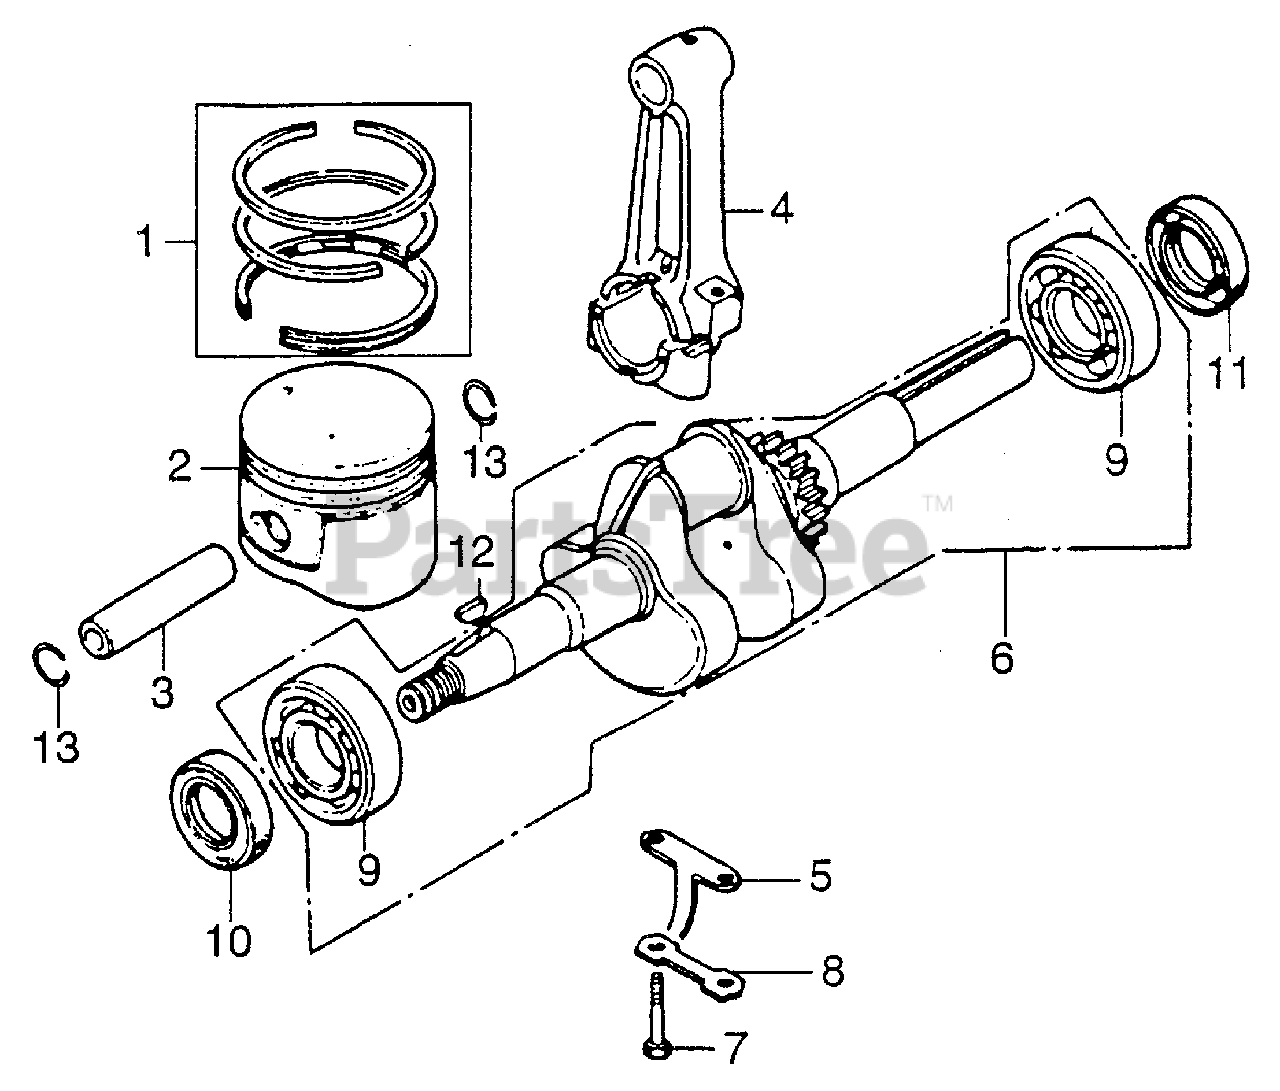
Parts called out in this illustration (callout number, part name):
1	RING SET, PISTON (STD)
1	RING SET, PISTON (OS 0.25) (OS)
1	RING SET, PISTON (OS 0.50) (OS)
1	RING SET, PISTON (0.75) (OS)
2	PISTON (STD)
2	PISTON (OS 0.25) (OS) (NOT AVAILABLE)
2	PISTON (OS 0.50) (OS)
2	PISTON (0.75) (OS)
3	PIN, PISTON
4	ROD, CONNECTING
5	DIPPER
6	CRANKSHAFT
7	BOLT, HEX. (6X37)
8	WASHER, TONGUED
9	BEARING, RADIAL BALL (62/22)
10	OIL SEAL (22X35X6)
11	OIL SEAL (22X41X6)
12	KEY, WOODRUFF (25X14)
13	CLIP, PISTON PIN (15MM)
